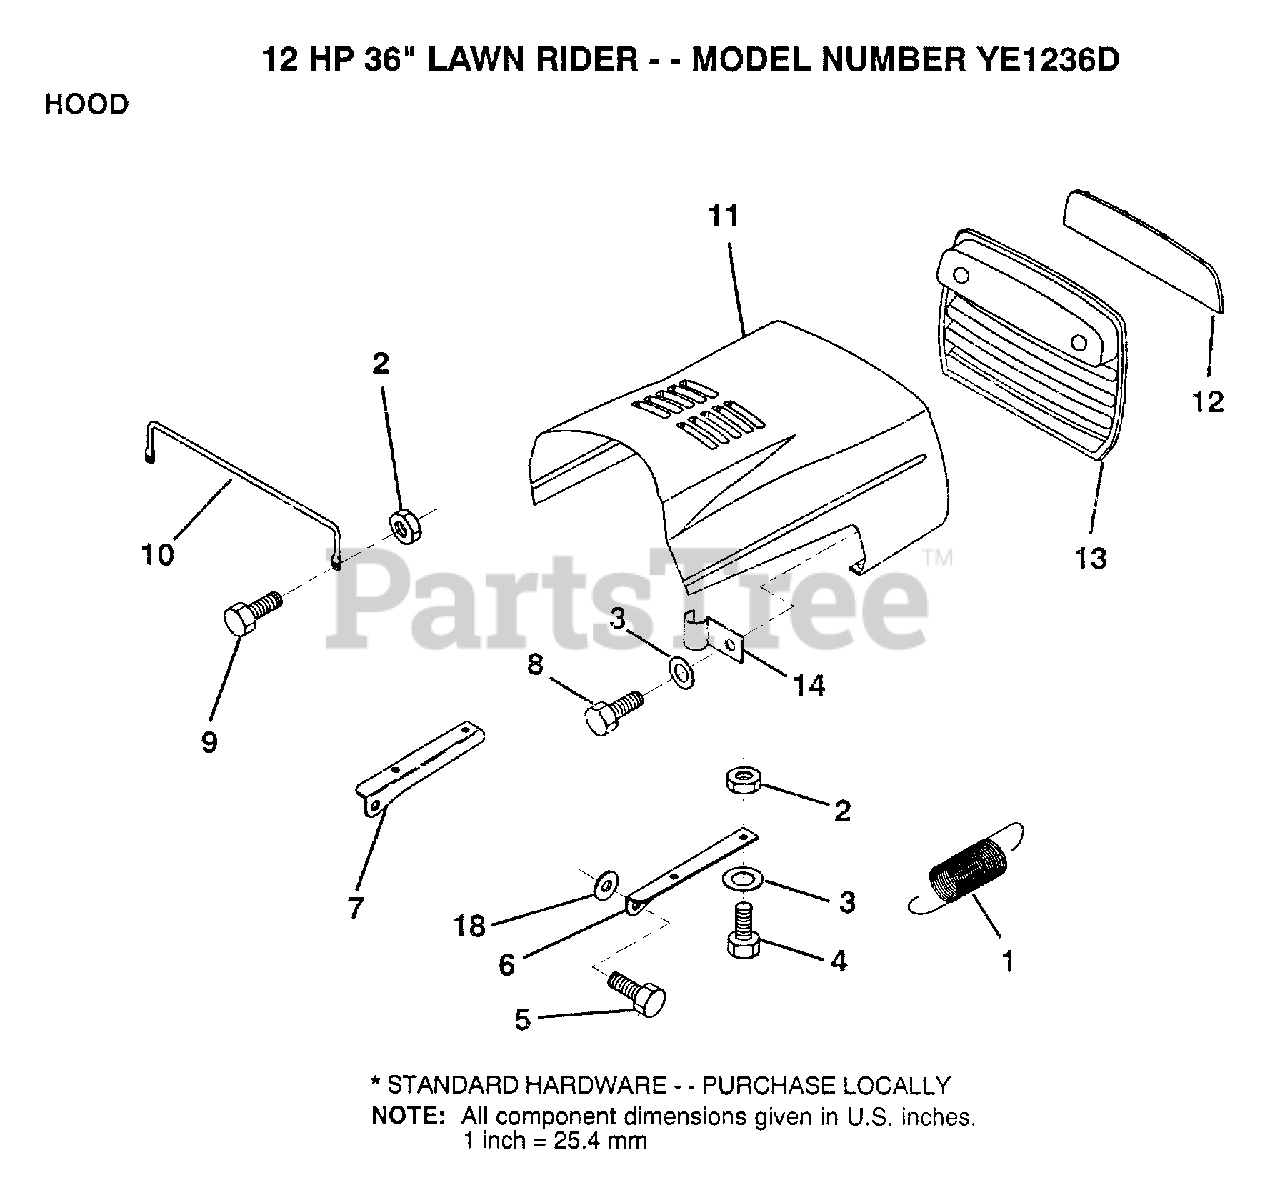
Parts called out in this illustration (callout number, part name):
1	EXT SPRING
2	NUT
3	WASHER
4	BOLT
6	BRKT HOOD RH
7	BRKT HOOD LH
10	"BRACE,HOOD"
11	HOOD
12	LENS
13	GRILL
14	CLIP T
16	NUT
18	WASHER
